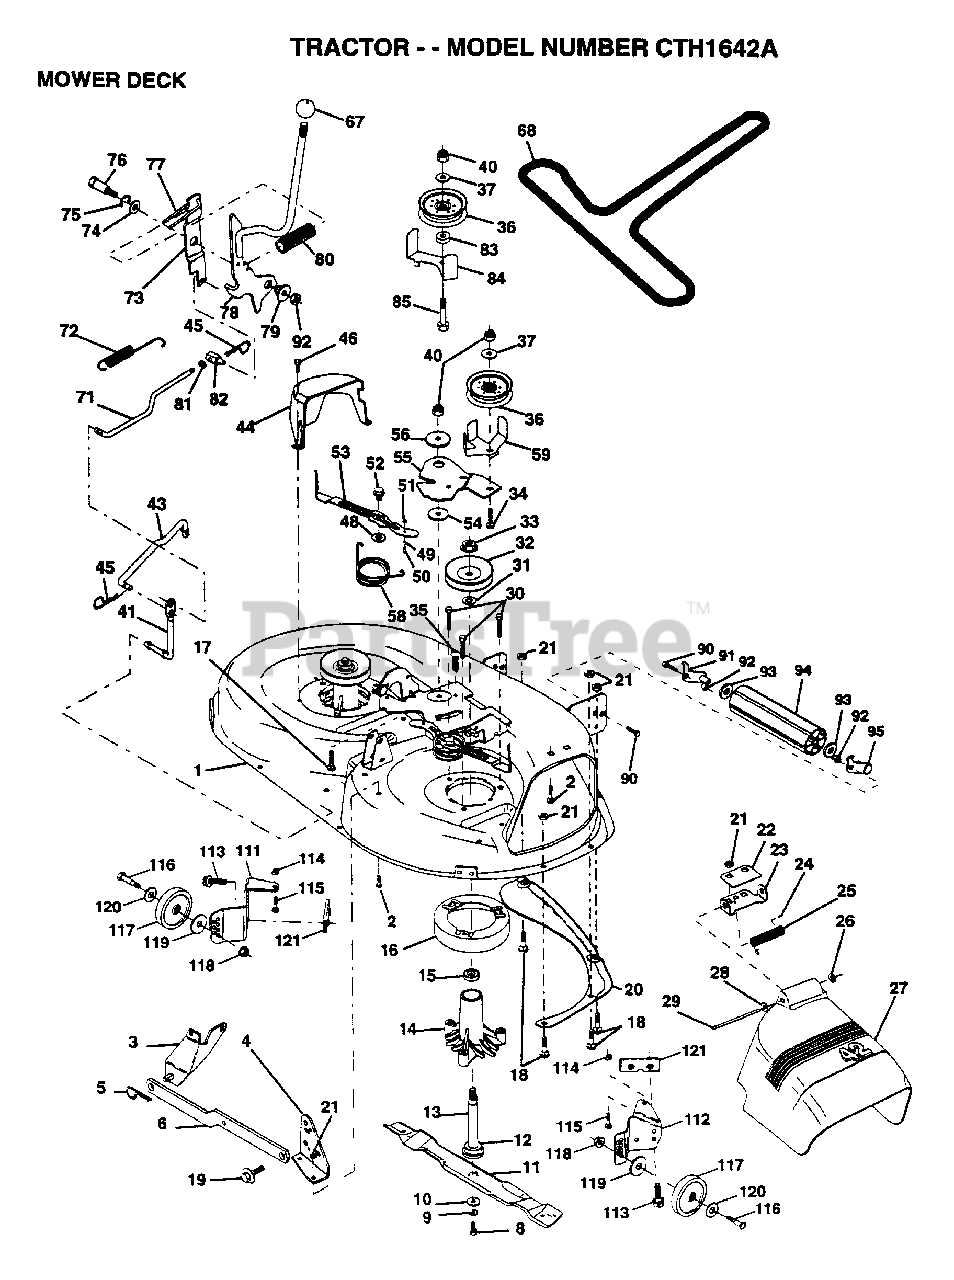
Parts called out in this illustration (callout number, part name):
1	DECK.WELD.42.
2	BOLT
3	BRKT ASM SWAY BAR
4	BRKT DECK SW BAR
8	BLADE BOLT
10	WASHER.HARD.BLADE
11	"BLADE.42"" HIPERF"
12	BEARING.BALL
14	HSG ASM MANDREL
15	BEARING
16	STRIPPER RND MWR
17	BOLT RDHD 3/8-16
18	BOLT
19	BOLT SHD 5/16-18
22	STIFFENER BRKT
23	DEFLECTOR BRKT
24	CAP-SLEEVE LT
25	SPRING TORSION
26	NUT PUSH M
27	DEFLECTOR.SHIELD
28	WASHER
29	HINGE ROD
31	WASHER
34	BOLT
35	XMAS TREE FASTNER
36	FLAT IDLER PULLEY
37	WASHER
41	PIVOT ROD
43	ROD CLUTCH W/NIBS
44	GUARD MAND LH BLK
45	RETAINER M
46	SCREW.1/4-20X5/8
48	HARD SMALL WASHER
50	SHOULDER BOLT
51	LOCKNUT
52	BOLT.SHLD.5/16-18
53	BRAKE PAD ARM ASM
54	HARDENED WASHER
56	SPACER RETAINER
58	SPRING TORSN BRAK
59	GUARD IDLER TUV
68	BELT.V.T-PATH
71	ROD CLUTCH 38/42
72	RETURN SPRING
73	CLUTCH ARM SECOND
74	WASHER
75	RING
76	SHOULDER BOLT
77	SPRING KEEPER
78	LEVER.CLU.PRIM.
79	BUSHING
81	NUT
82	TRUNION ADJ
83	WASHER
85	BOLT
90	BOLT
92	NUT
93	WASHER
113	SCREW
116	BOLT M
117	WHEEL.GAGE.BLK.PL
118	LOCKNUT
119	WASHER
120	WASHER
121	BRACKET.EXTRD.GWL
